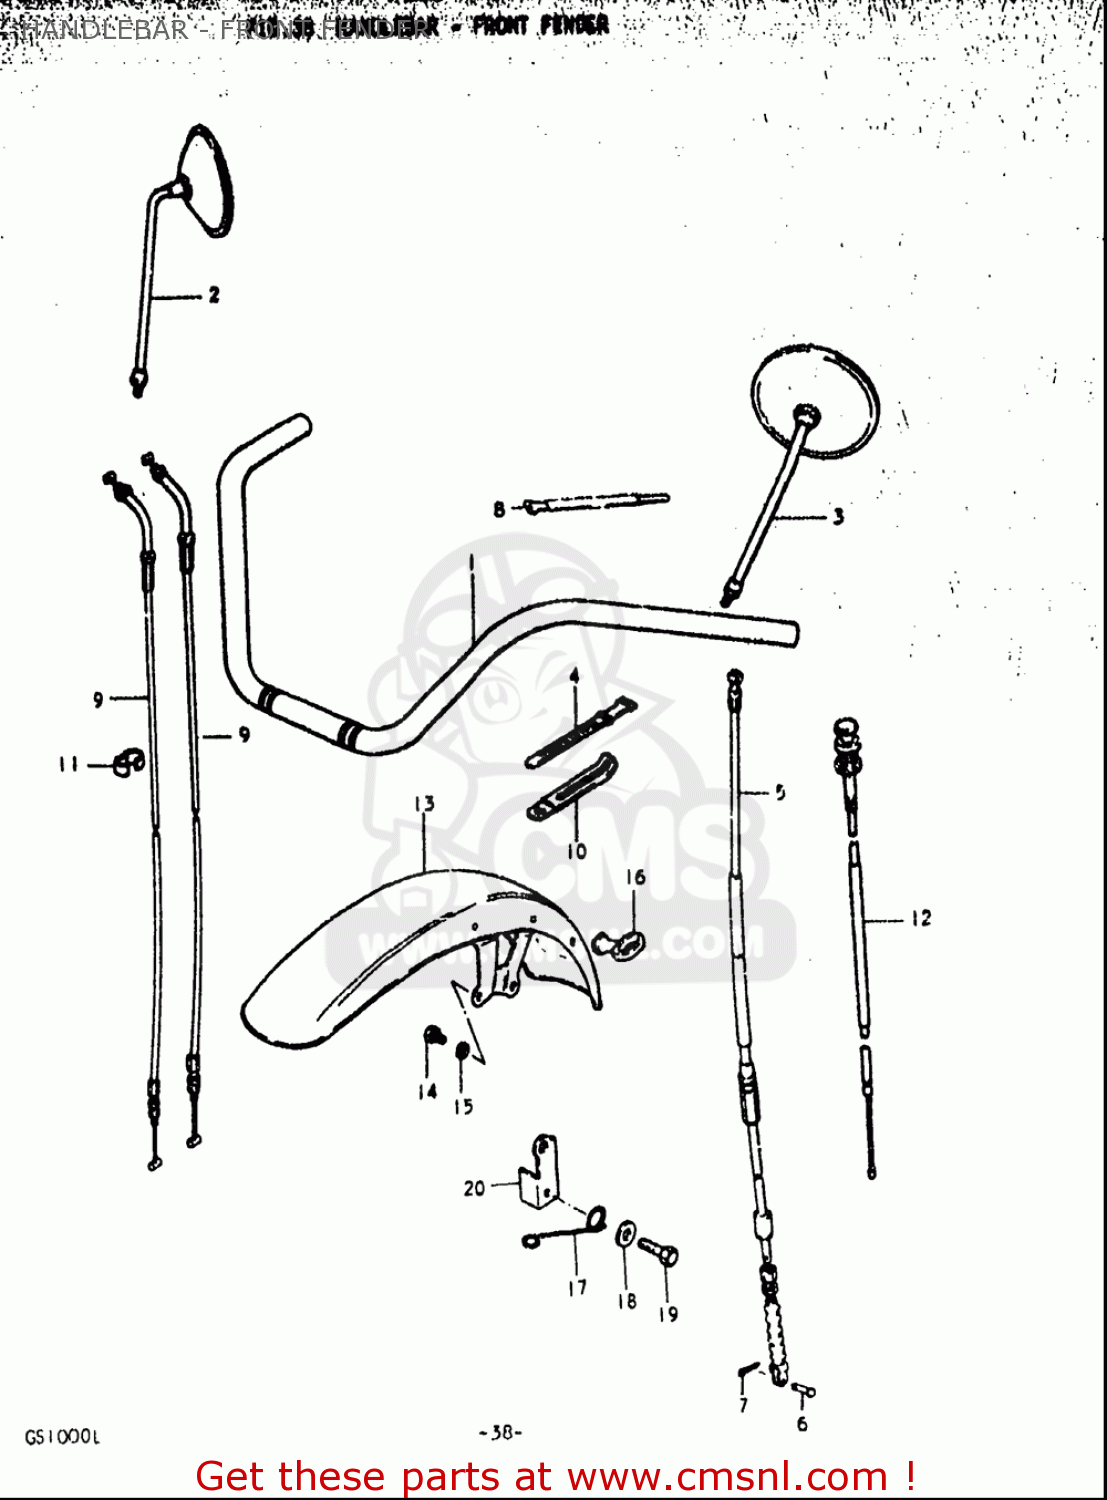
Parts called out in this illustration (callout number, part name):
1	HANDLEBAR
2	MIRROR ASSY,RR VIEW,R
3	MIRROR ASSY,RR VIEW,L
4	CLAMP(L:120)
5	CABLE ASSY,CLUTCH
6	PIN(L:15)
7	PIN
8	CLAMP
9	CABLE ASSY,THROTTLE
10	CLAMP(L:65)
11	CLIP
12	CABLE ASSY,STARTER
13	FENDER,FR
14	BOLT
15	WASHER,LOCK
16	GUIDE,CABLE
17	GUIDE,SPEEDOMETER CABLE
18	WASHER
19	BOLT
